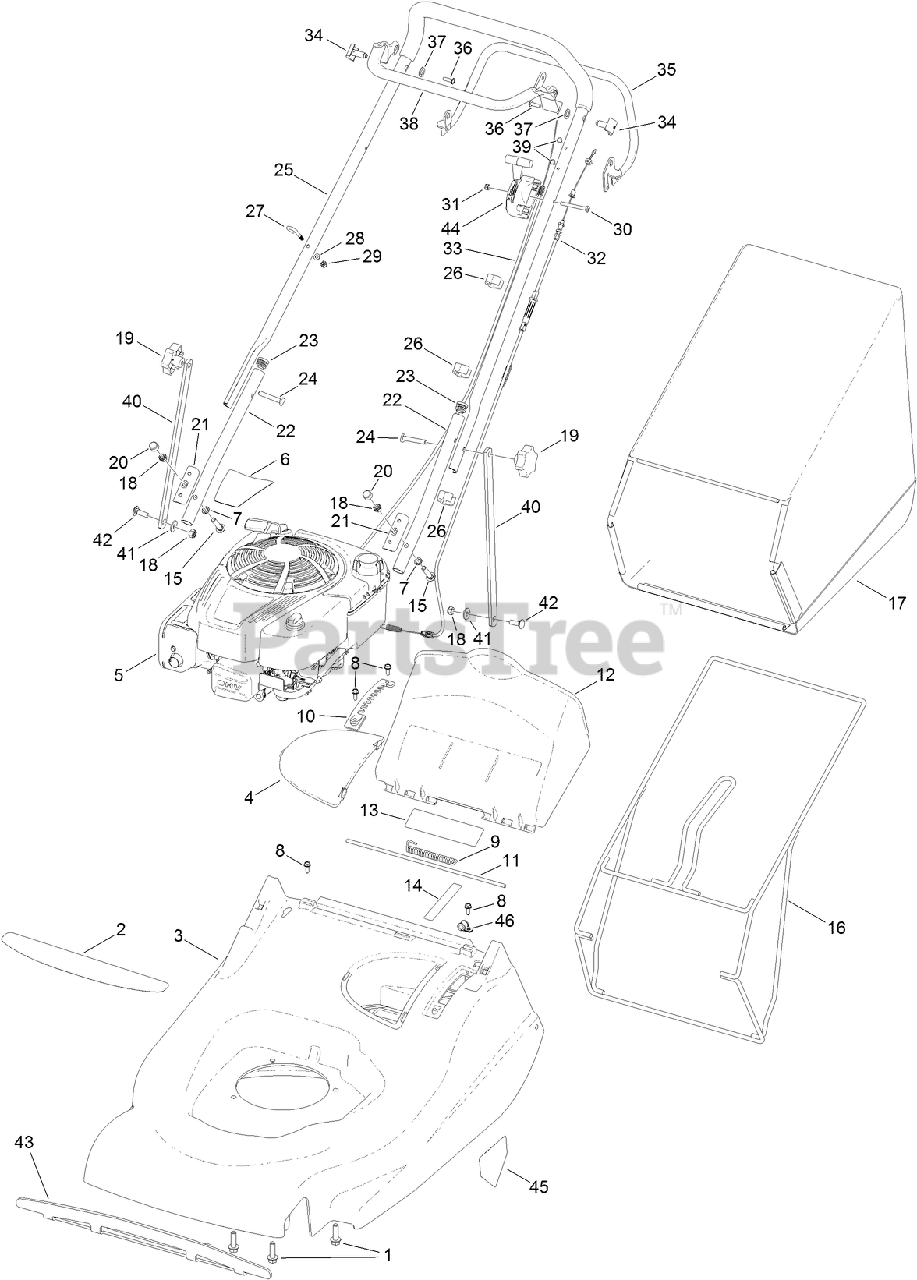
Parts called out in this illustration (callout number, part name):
1	SCREW-TAPTITE, UNC
2	DECAL-DECK
4	COVER-BATTERY
5	ENGINE-BRIGGS, 121Q020130F1
6	DECAL-ENGINE
7	GRIP-FIX
8	SCREW-TAPTITE
9	SPRING-DEFLECTOR
10	RATCHET-PLATE, HOC
11	ROD-DEFLECTOR
12	DEFLECTOR-REAR
13	DECAL-SAFETY
14	DECAL HOC
15	BOLT-COACH
16	FRAME-GRASSBAG
17	GRASSBAG-FABRIC
18	NUT-HEX, NI
19	KNOB-HANDLEBAR
20	CAP-NUT
21	PLATE-CLAMP, HANDLEBAR
22	HANDLEBAR-LOWER
23	PLUG-TUBE
24	BOLT
25	HANDLEBAR-UPPER
26	GUIDE-CABLE
27	GUIDE-ROPE
28	WASHER-PLAIN
29	NUT-NYLOC
30	SETSCREW
31	NUT-NYLOC
32	CABLE-ENGINE, BRAKE
33	CABLE-CLUTCH
34	PIN-PIVOT
35	LEVER-CLUTCH
36	SCREW
37	WASHER-NYLON
39	FASTENER-DRIVE
40	BRACE-HANDLEBAR
41	WASHER
42	BOLT-COACH
43	BAR-BUMP, PLATE
44	CONTROL-SPEED, ENGINE
45	DECAL-DANGER
46	CLIP-CABLE
